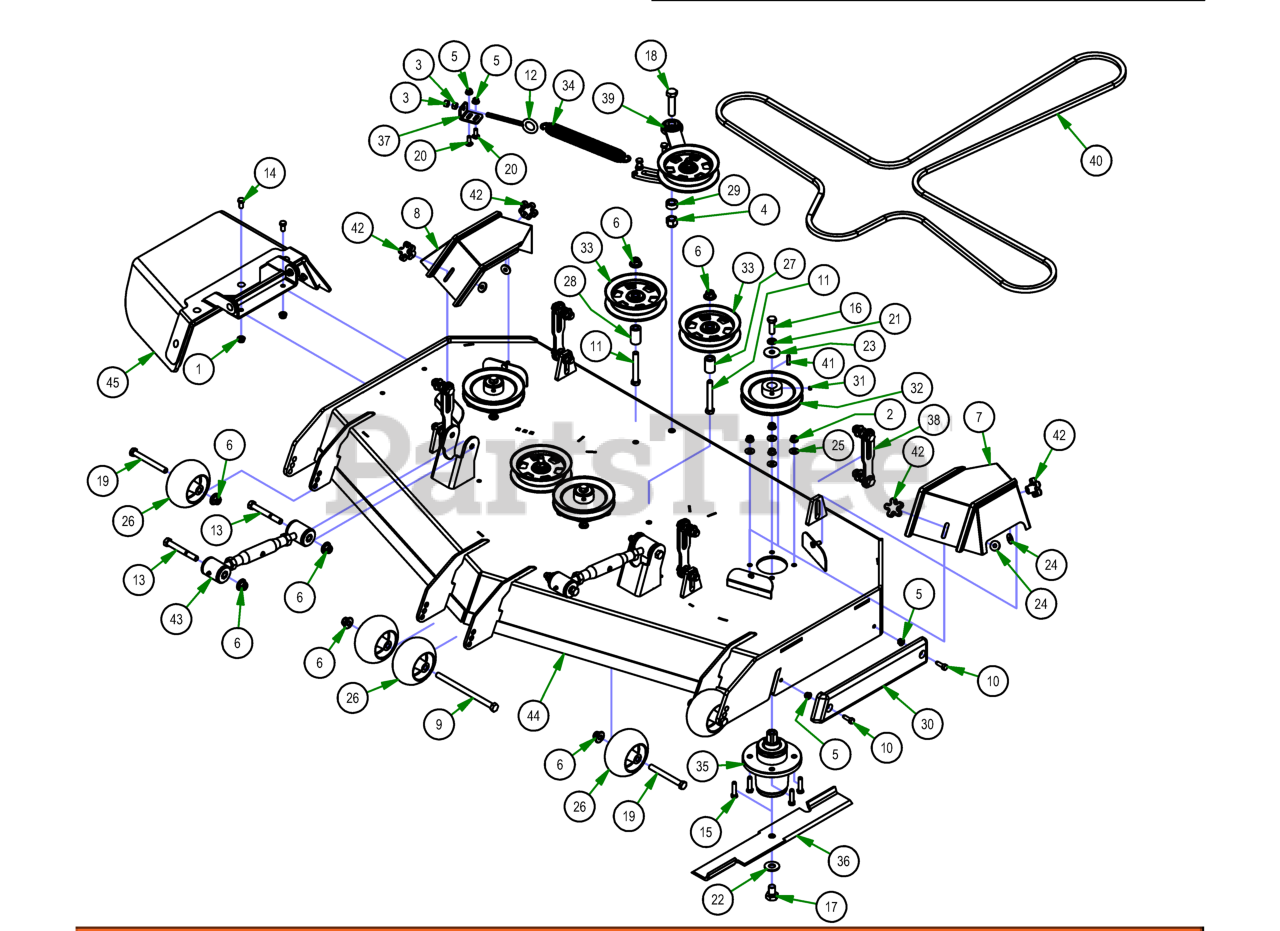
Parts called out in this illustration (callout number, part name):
1	3/8" Flange Nut
2	3/8-16 NYLON INSERT FLANGE LOCKNUT (GR.F) ZINC
3	3/8" Hex Nut
4	5/8 Std NC Nylock Nut
5	5/16" Nylon Flange Nut
6	1/2-13 NYLON INSERT FLANGE LOCKNUT ZINC
7	2019 61" Outlaw Gen2 Pulley Cover Left
8	2019 61" Outlaw Gen2 Pulley Cover Right
9	1/2-13 x 8 Hex Bolt Grade 5
10	5/16-18 x 1 GR 5 Hex Bolt Zinc
11	1/2 x 3 1/2 Flange Bolt Grade 8
12	4" 3/8-16 Eye Bolt
13	1/2" x 4" Bolt (Grade 8)
14	3/8" x 3/4" Hex Bolt
15	3/8-16 X 1-1/2 HEX CAP SCREW (GR.5) ZINC
16	1/2"-20 x 1 1/2 - Grade 5 Fine Thread Bolt
17	5/8" x 1 1/2" Grade 8 Hex Bolt (Fine)
18	5/8" x 2 1/2" Grade 5 Hex Bolt (Coarse)
19	1/2" x 4 1/2" Bolt
20	5/16" x 7/8" Carriage Bolt
21	1/2" Lock Washer
22	5/8'' Flat Washer
23	1/2" Belleville Washer
24	.360 ID Plastic Washer-Black
25	5/16 USS FLAT WASHER (7/8 OD) ZINC
26	2019 Deck Wheel
27	.502 ID X .750 OD X 1.500 Long Spacer
28	1 3/4" Pulley Spacer
29	5/8" x 1/" Collar W/One Set Screw
30	REVISED TRIM BUMPER_20180226
31	5/16 Set Screw
32	6 1/4" Drive Pulley
33	5-3/4 Idler Pulley
34	2019 Outlaw Gen2 Deck Spring
35	OUTLAW SPINDLE ASSEMBLY
36	61 inch Fusion Blade
37	2019 Deck Eye Bolt Tab
38	Deck Hangar Assembly
39	2019 Renegade Deck Idler
40	Deck Belt for 61" Renegade
41	1/4" x 1" Key
42	5/16" Knob
43	Turnbuckle
44	2019 Sloped 61" Deck
45	2019 Outlaw Gen2 Chute Assembly
